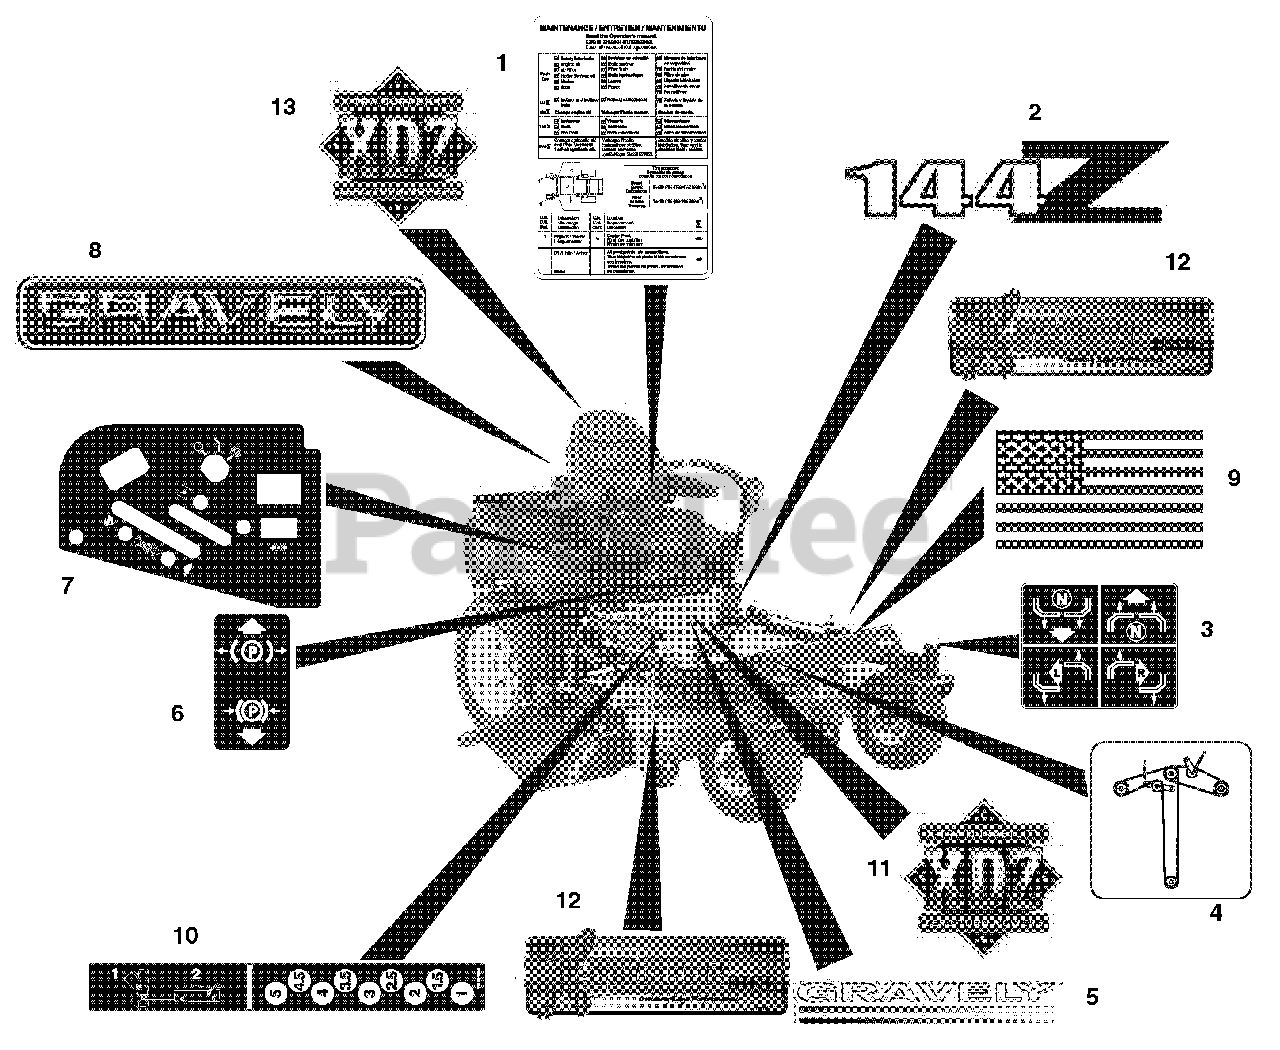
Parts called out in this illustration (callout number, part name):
1	Decal, Service Instructions
2	Decal, PM 152Z (991028, 030, 031)
3	Decal, Instructional Steering
4	Decal, Belt Diagram
5	Decal, ZT Hood
6	Decal, Parking Brake Lever
7	Decal, Control Panel
8	Decal, 15" Gravely Logo (991026, 027, 028, 031)
9	Decal, American Flag
10	Decal, Height of Cut
11	Decal, 3" XDZ (991026, 027, 028, 031)
12	Decal, X-Factor
13	Decal, 5" XDZ (991026, 027, 028, 031)
